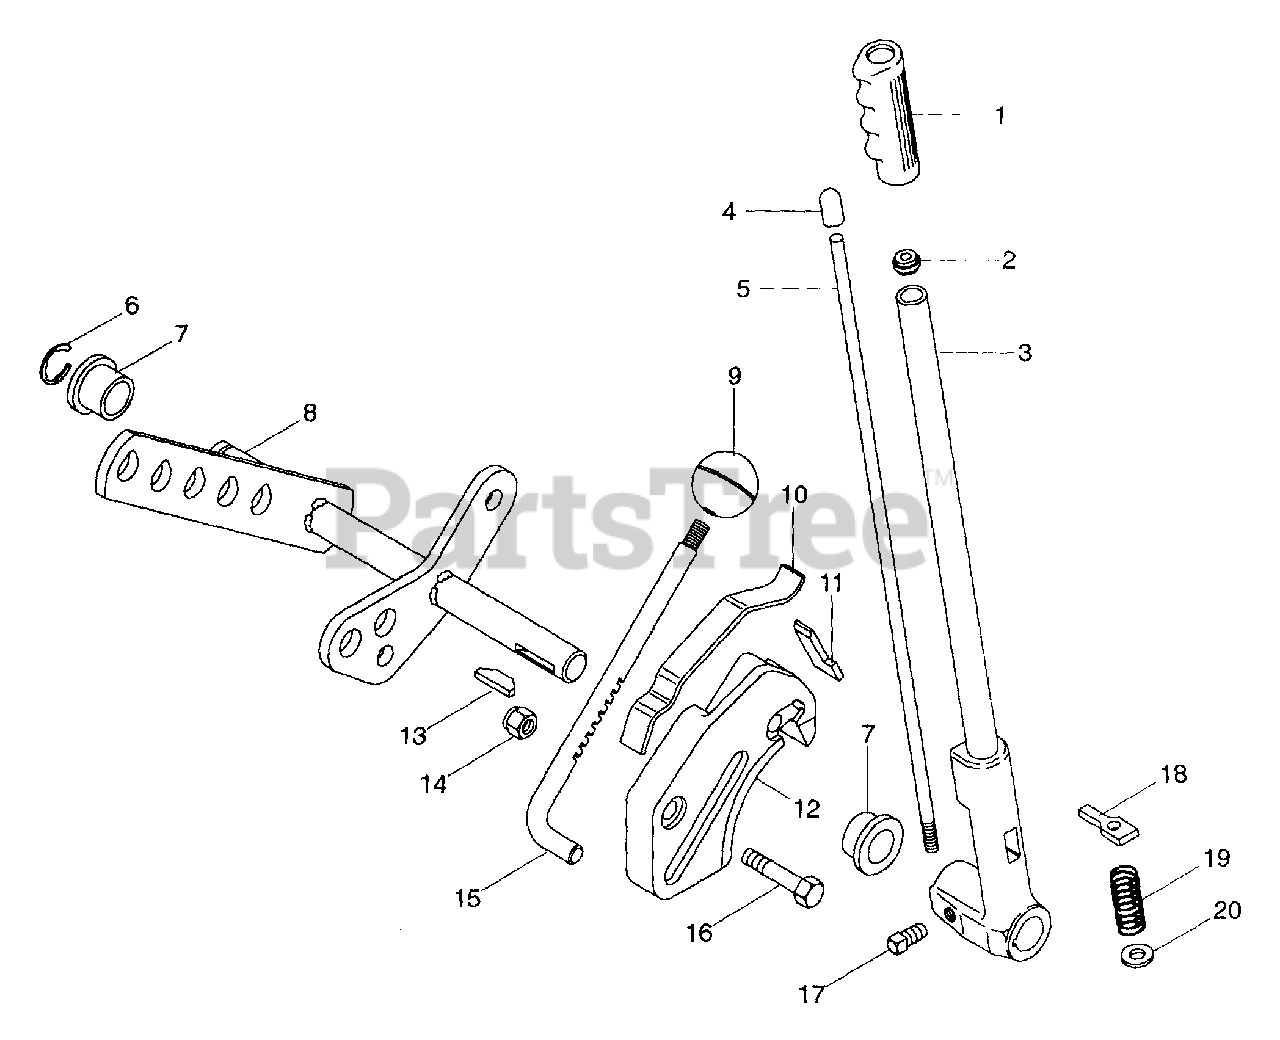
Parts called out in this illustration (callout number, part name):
1	Grip, Flex
2	Guide, Push Rod
3	Assembly, Lever Lift
4	Tip, Push Rod
5	Rod, Lever Push
6	Ring-Retaining-External .835 x .056
7	Bushing-Flange 1.020 x 1.385 x .75 x 1.75
8	Shaft, Lift Lever Weldment
9	Knob, Control .438-20 x .50
10	Spring, Stop
11	Stop, Lever
12	Casting, Locator
13	Key, Woodruff .25 x 2.13
14	Nut-Locking-Nylon .375-16 Grade 2
15	Rod, Lever Stop
16	Bolt-Hex .38-16 x 1.25 Grade 5
17	Screw-Set .38-16 x .50
18	Pawl, Lever
19	Spring-Compression .067 x .72 x 2.0
20	Washer-Flat-Steel .426 x .978 x .084
